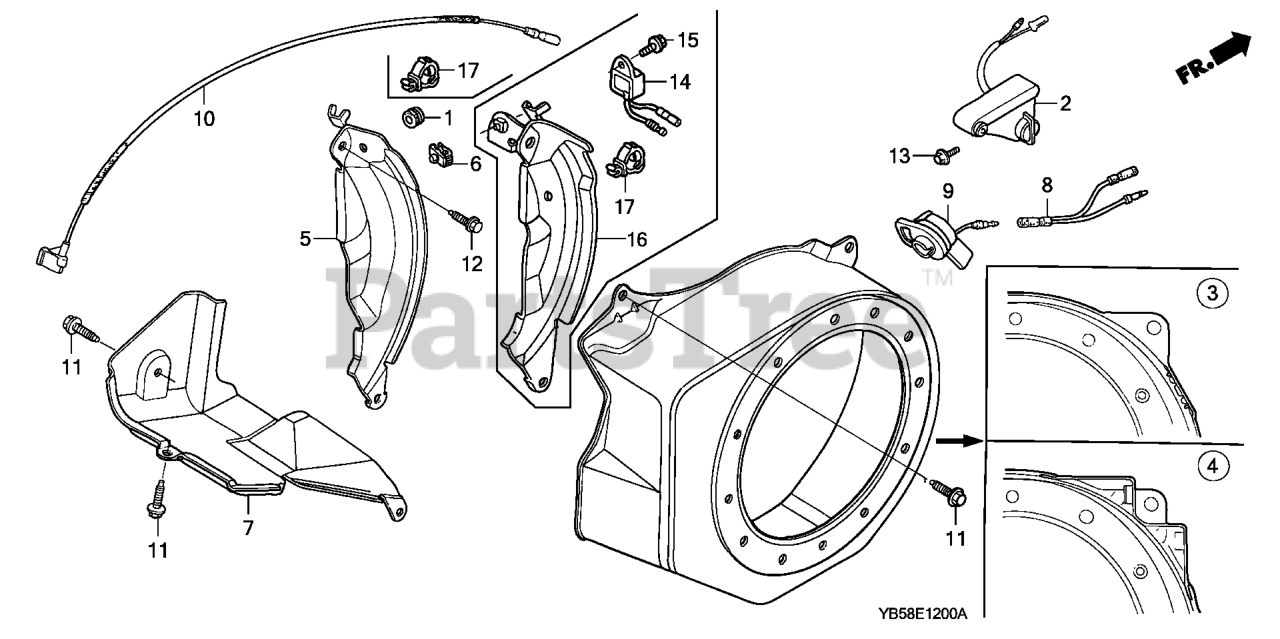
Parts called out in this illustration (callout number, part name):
3	COVER, FAN *R8* (BRIGHT RED)
3	COVER, FAN *R280* (POWER RED)
5	PLATE, SIDE (STD)
7	SHROUD
9	SWITCH ASSY., ENGINE STOP Use from Engine SN 2092216 to 2359126.
10	WIRE, STOP SWITCH (370MM)
11	BOLT, FLANGE (6X12) (CT200)
12	BOLT, FLANGE (6X20) (CT200)
